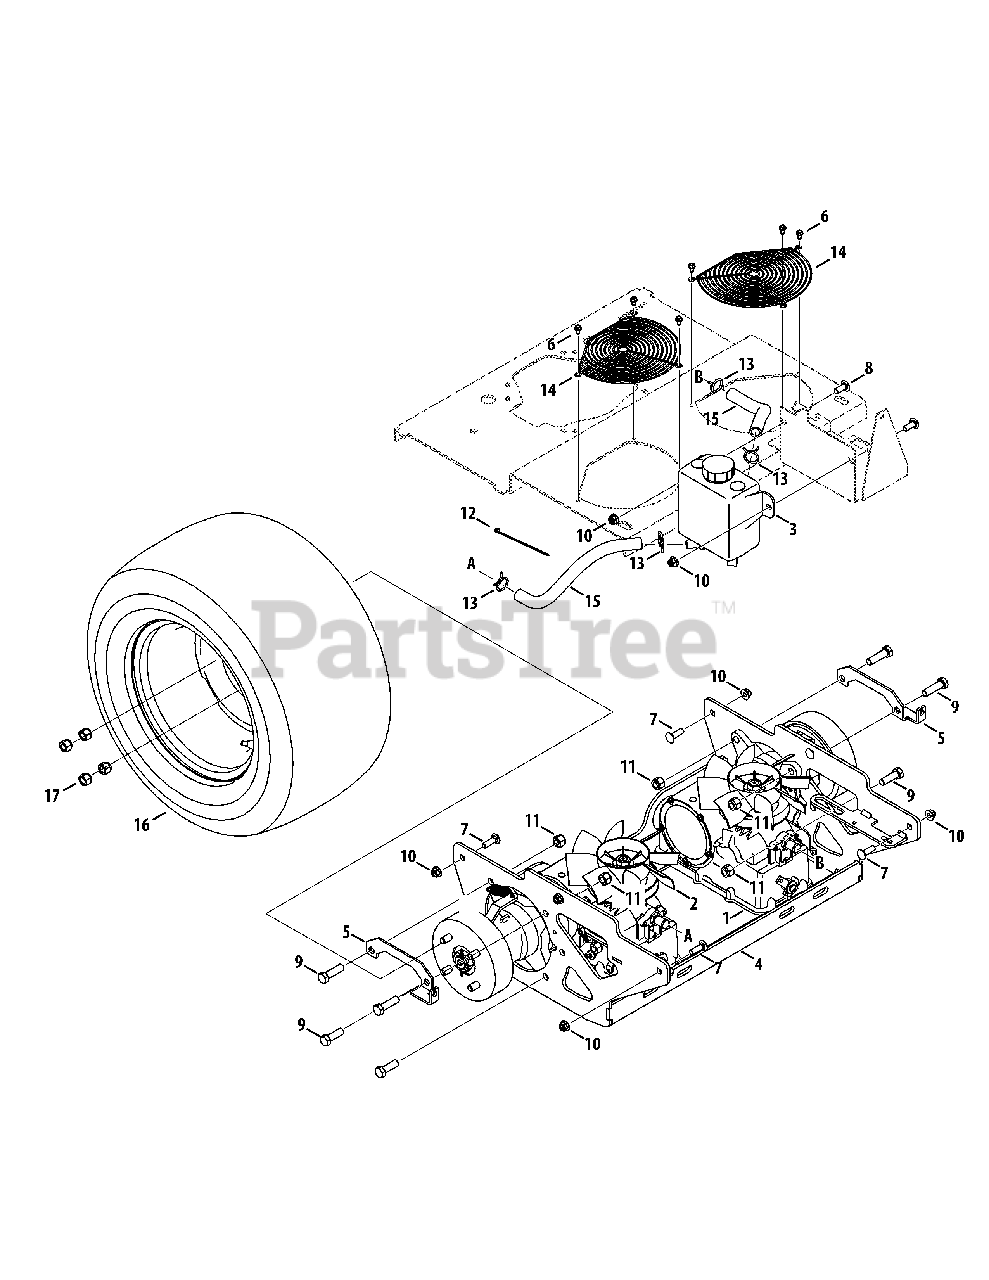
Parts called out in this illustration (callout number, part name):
1	Transmission, LH
2	Transmission, RH
3	Hydro Tank Assembly
4	Transmission Bracket Assembly
5	Transmission Brake Bracket
6	Screw, 10-24 x .500
7	Carriage Bolt, 3/8-16 x 1.25
8	Carriage Bolt, 3/8-16 x 1.00
9	Hex Cap Screw, 1/2-13 x 1.50
10	Nut, 3/8-16, Flangelock
11	Nut, 1/2-13, Flangelock
12	Cable Tie
13	Hose Clamp, .875
15	Hose, 5/8 ID x 12.00 LG
16	Wheel Assembly, 24 x 9.5-12 (48" deck)
16	Wheel Assembly, 24 x 12-12 (60" deck)
17	Lug Nut, 1/2-13
